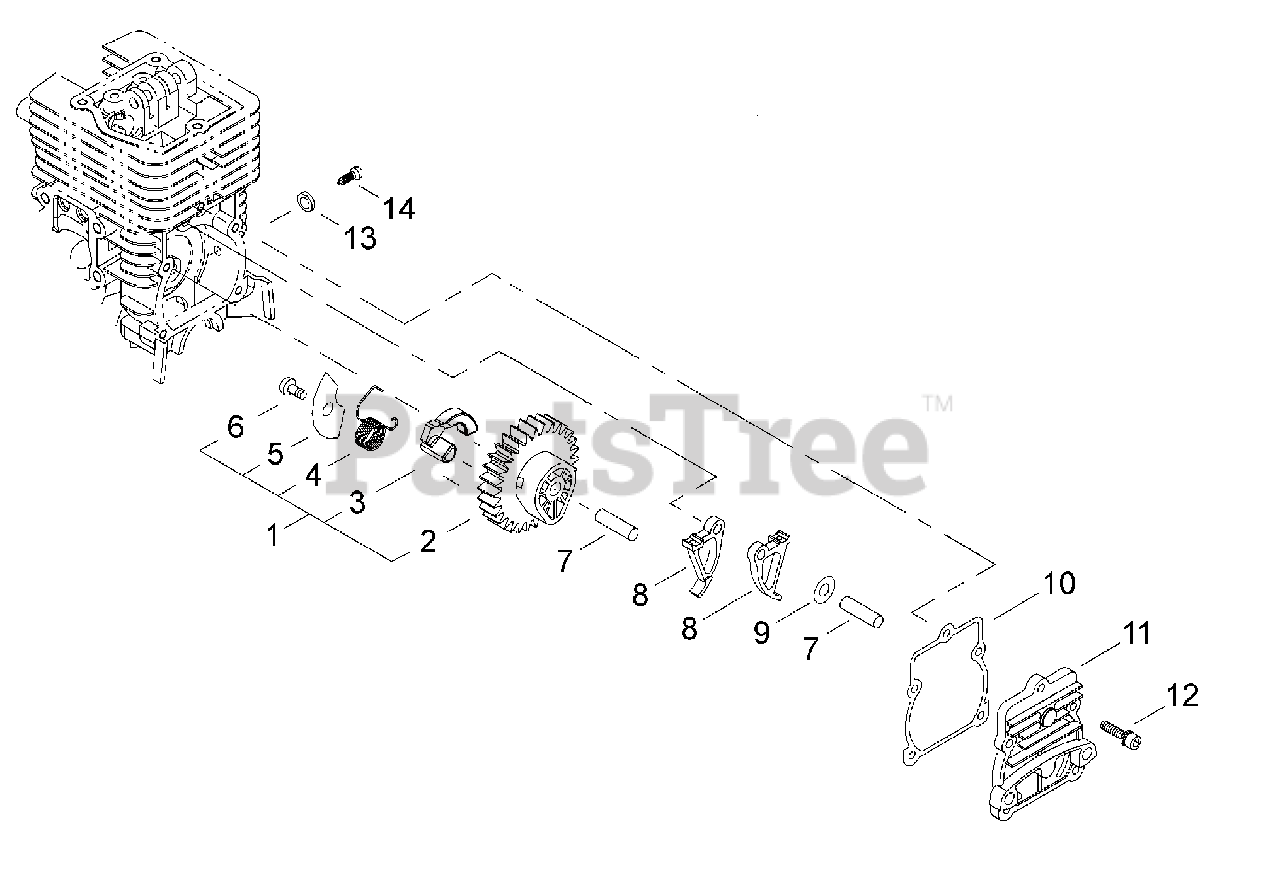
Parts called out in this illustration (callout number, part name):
1	CAM GEAR ASSY
2	GEAR, CAM
3	WEIGHT
4	SPRING
5	PLATE, COVER
6	SCREW, TAPPING 4×6
7	PIN, LOCATING Ø5×29.8 MM
8	FOLLOWER, CAM
9	WASHER 5 MM
10	GASKET, CAM GEAR
11	COVER, CAM GEAR
12	BOLT M4×14
13	WASHER Ø10ר5.5×2
14	SCREW M5
